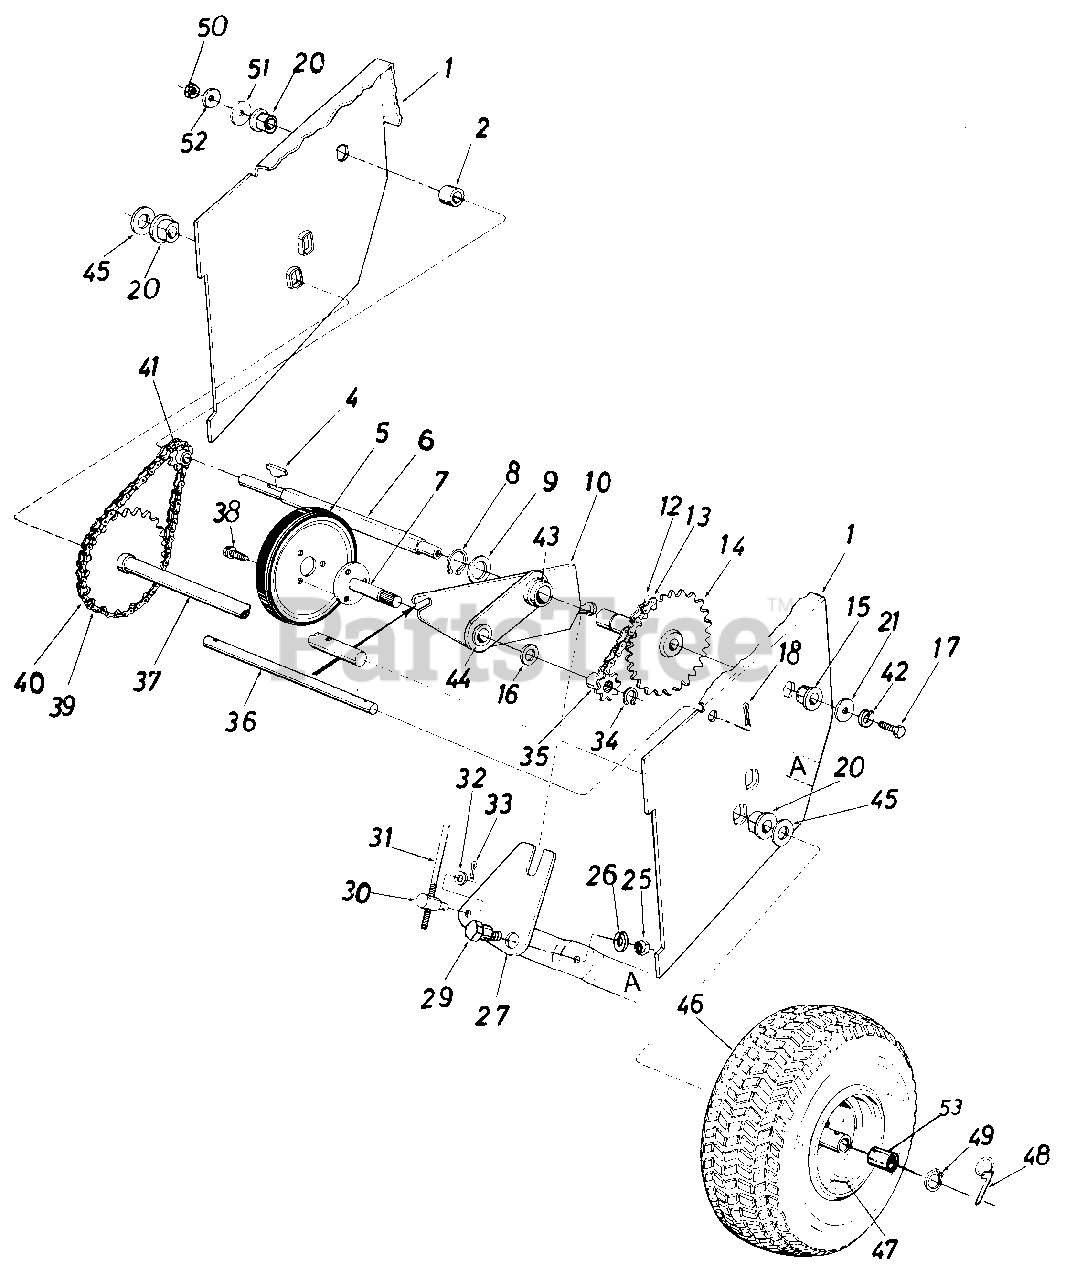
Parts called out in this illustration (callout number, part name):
1	Frame Ass'y.
2	Spacer.50" I.D. x .75" O.D. x .78" Lg.
4	#4 Hi-Pro Key 3/32 x 5/8" Dia.
5	Friction Wheel Ass'y.
6	Hex Shaft
7	Friction Wheel Mounting Plate Ass'y.
8	Snap Ring 1.00" Dia. Shaft
9	Fl-Wash 1.00" x 1.63" O.D. x .03
10	Sliding Bracket Ass'y.
12	#41 Chain 1/2" Pitch x 35 Links
13	Master Link for #41 Chain
14	32 Teeth Sprocket Ass'y.
15	Hex Flange Brg. .630" I.D.
16	Fl-Wash. .62" I.D. x 1.00" O.D. x .06
17	Hex Lock Bolt 5/16-18 x .62" Lg.*
18	Cotter Pin 3/32" Dia. x .75" Lg.*
20	Flange Brg. w/Flats .755" I.D.
21	Fl-Wash. .34" I.D. x 1.12" O.D. x .125
25	Hex Jam Nut 3/8-16 Thd.
26	L-Wash. 3/8" I.D.
27	Shifting Linkage Bracket
29	Shld. Bolt .625" Dia. x .170" Lg.
30	Adjustment Ferrule
31	Shifting Rod 5/16" Dia. x 32.50" Lg.
32	Fl-Wash. .34" I.D. x .64" O.D. x .06
33	Cotter Pin 3132" Dia. x .75" Lg.
34	Snap Ring .562" Dia. Shaft
35	Sprocket 7 Teeth x .50" Pitch
36	Shaft .50" Dia. x 9.50" Lg.
37	32 Teeth Wheel Axle Ass'y.
38	Hex Wash. Hd. Self-Tap Scr. 5/16-24 x .50" Lg.
39	#420 Chain 112" Pitch x 39 Links
40	Master Link for #420 Chain
41	8 Teeth Center Sprocket
42	L-Wash. 5/16" I.D.
43	Plastic Bearing
44	Bronze Bearing
45	Fl-Wash. .76" I.D. x 1.49 O.D.
46	Wheel Ass'y. Comp. 13 x 5.0
47	Air Valve
48	Klick Pin
49	Snap Ring .75 Dia.
50	Hex Ins. L-Nut 1/2-20 Thd.
51	Fl-Wash. .53 I.D. x 1.25 O.D. x . 1 0
52	Bell-Wash. .50 I.D. x 1.0 O.D. x .075
53	Sleeve Bearing
